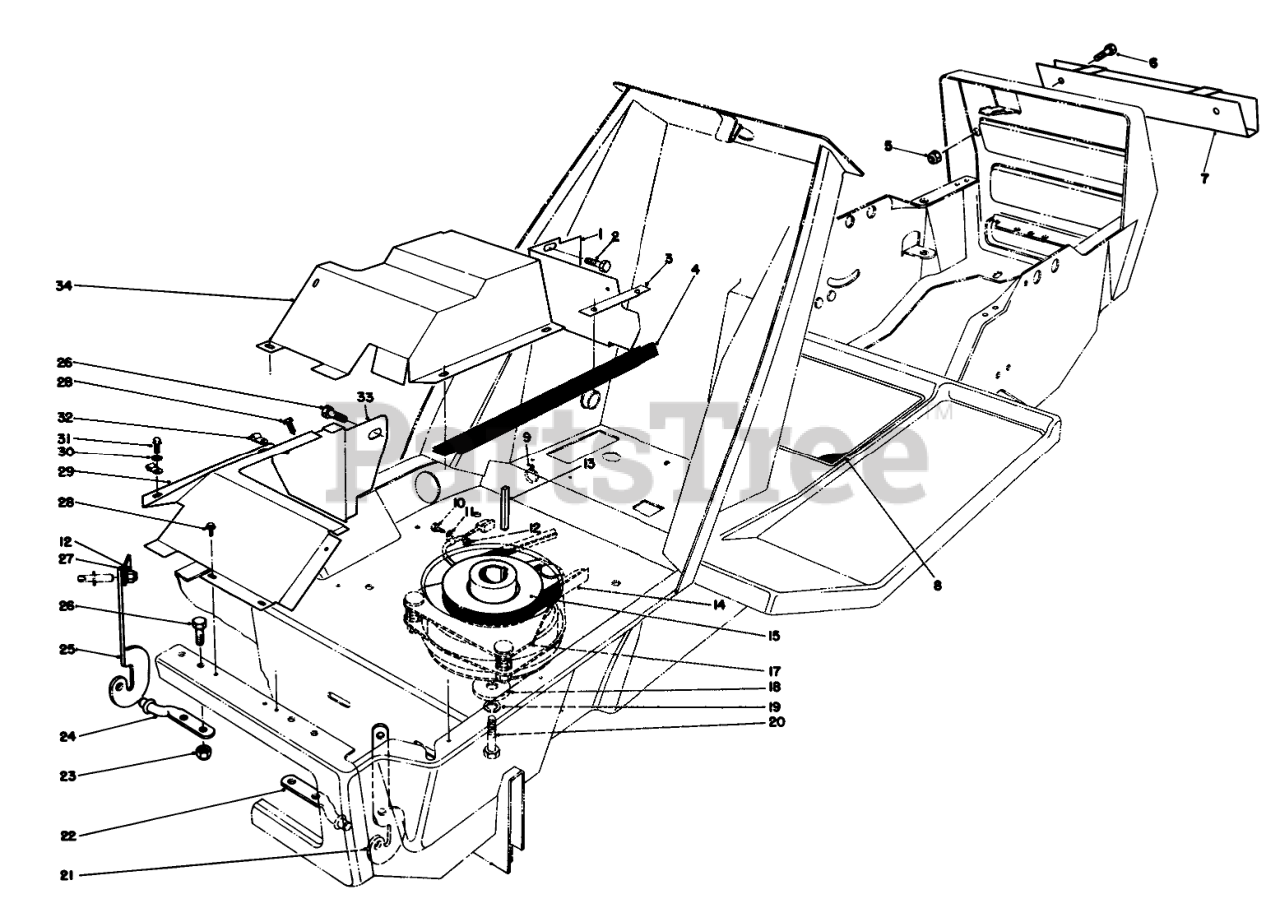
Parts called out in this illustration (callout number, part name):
1	L/H EXH SHIELD SUPT B
2	SCREW-HH
3	HOOD SEAL STRAP-PLT
4	LOWER HOOD SEAL
5	NUT-LOCK, NI
6	SCREW-HH
7	ADAPTER CHANNEL WA B
8	INSTRUCTION DECAL
9	TIE-MOUNT, PUSH
10	SCREW-HH
11	CLAMP
12	NUT-LOCK, NI
13	KEY-SQUARE
14	V BELT
15	Pulley
17	BRAKE CLUTCH ASM
18	WASHER-CLUTCH
19	WASHER-LOCK
20	SCREW-HH
21	L.H. HINGE BRACKET
22	LH HOOD HINGE PIN
23	NUT-LOCK, CONE
24	RH HOOD HINGE PIN
25	RH HINGE BRKT
26	SCREW-HH
27	SCREEN SUPT BRKT
28	SCREW-HWHTF
29	R/H HEAT SHIELD B
30	WASHER-FLAT
31	SCREW
32	CABLE CLAMP
33	R/H HEAT SHLD SUPT B
34	L/H HEAT SHIELD WA B
